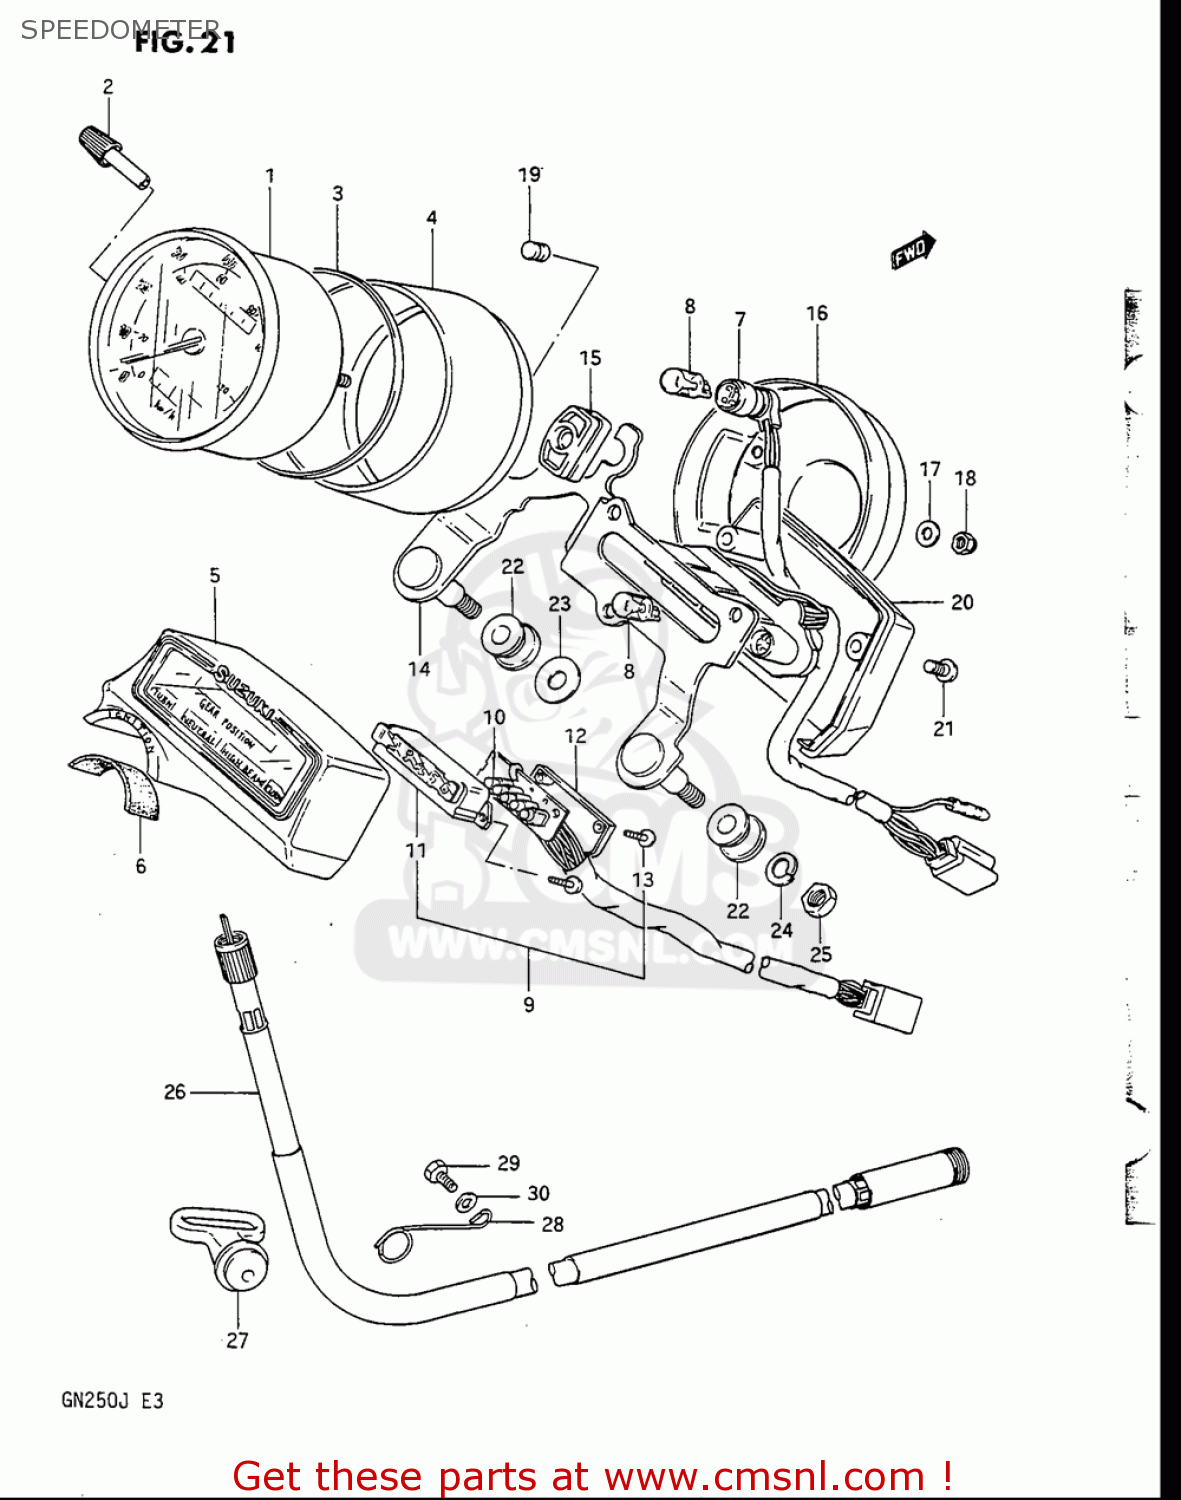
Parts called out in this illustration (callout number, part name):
2	KNOB
3	CUSHION
4	COVER,SPEEDOMETER
6	SEAL,IGNITION SWITCH
8	BULB(12V3.4W,T10)
10	BULB(14V1.12W)
11	CASE,GEAR INDICATOR
12	COVER,LWR
13	SCREW
15	CUSHION,METER
16	ORNAMENT,SPEEDOMETER
17	WASHER
18	NUT
20	COVER,PILOT BOX,UNDER
21	SCREW
22	CUSHION,METER BRACKET
23	WASHER(8.5X28X1.6)
24	WASHER,LOCK
25	NUT
26	CABLE ASSY,SPEEDOMETER
27	GUIDE,CABLE
28	CLAMP,SPEEDOMETER CABLE
29	BOLT
30	WASHER
